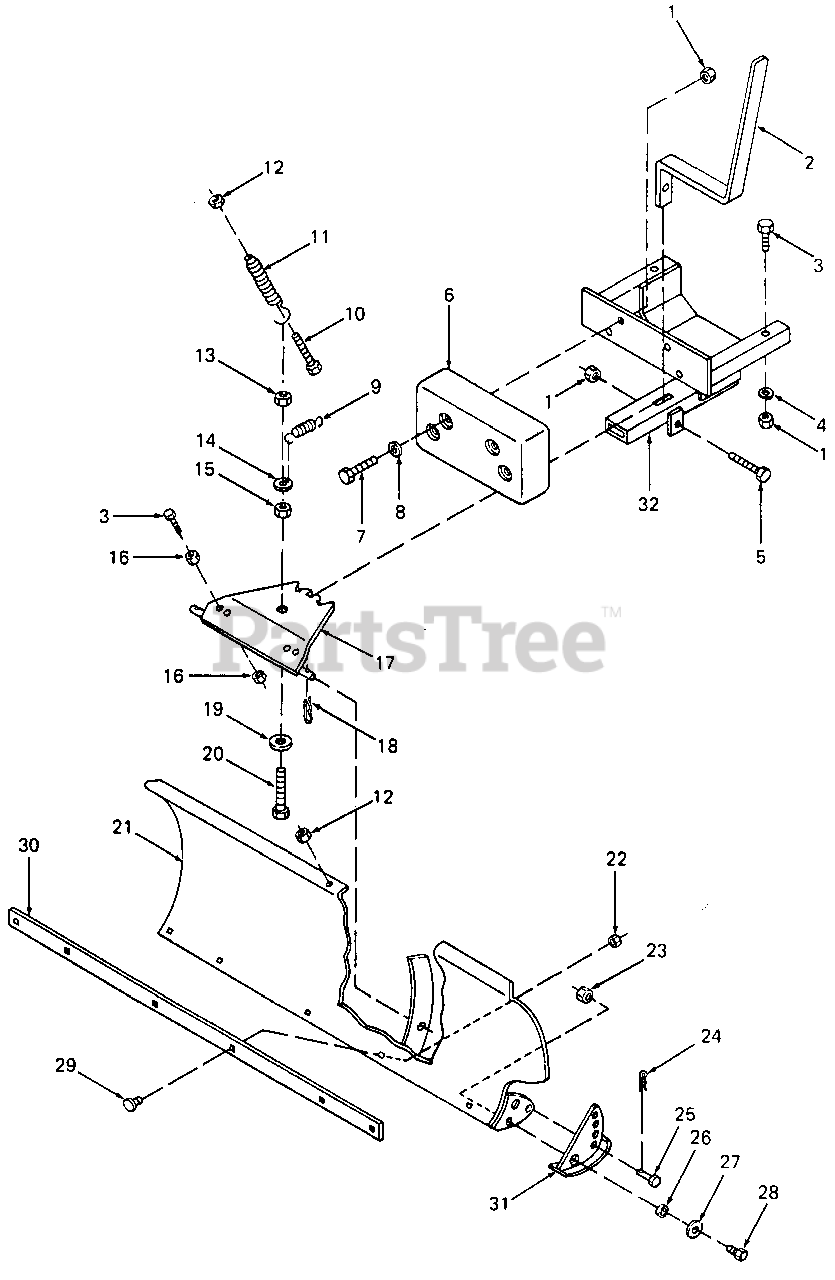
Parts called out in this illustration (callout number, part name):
1	Nut, Lock, 1/2-13
2	Handle, Dozer Latch
3	Bolt, Hex, 1/2-13 X 2
4	Washer, Lock, 1/2
5	Bolt, Hex, 1/2-13 X 4
6	Weight, Front Counter
7	Bolt, Hex, 1/2-13 X 5
8	Washer, Flat, 1/2
9	Spring, Angle Lock
10	Bolt, Hex, 3/8-16 X 4-1/2
11	Spring, Blade Adjustment
12	Nut, Hex Plain, 3/8-16
13	Nut, Lock, 3/4-10
14	Washer, Flat, 3/4 (Special)
15	Nut, Jam, 3/4-10
16	Nut, Jam, 1/2-13
17	Plate Assembly, Pivot
18	Cotter, Hairpin, 1/8 Dia
19	Washer, Flat, 3/4
20	Bolt, Hex, 3/4-10 X 4 (Special)
21	Blade Assembly, 48 Inch
22	Nut, Lock, 5/16-18
23	Nut, Lock, 3/8-16
24	Cotter, Hairpin, 3/32 Dia
25	Pin, Clevis, 5/16 X 3/4
26	Spacer
27	Washer, Flat, 3/8
28	Bolt, Hex, 3/4-16 X 1
29	Bolt, Carriage, 5/16 X 3/4
30	Plate, Wear, 48 Inch
31	Shoe, Skid
